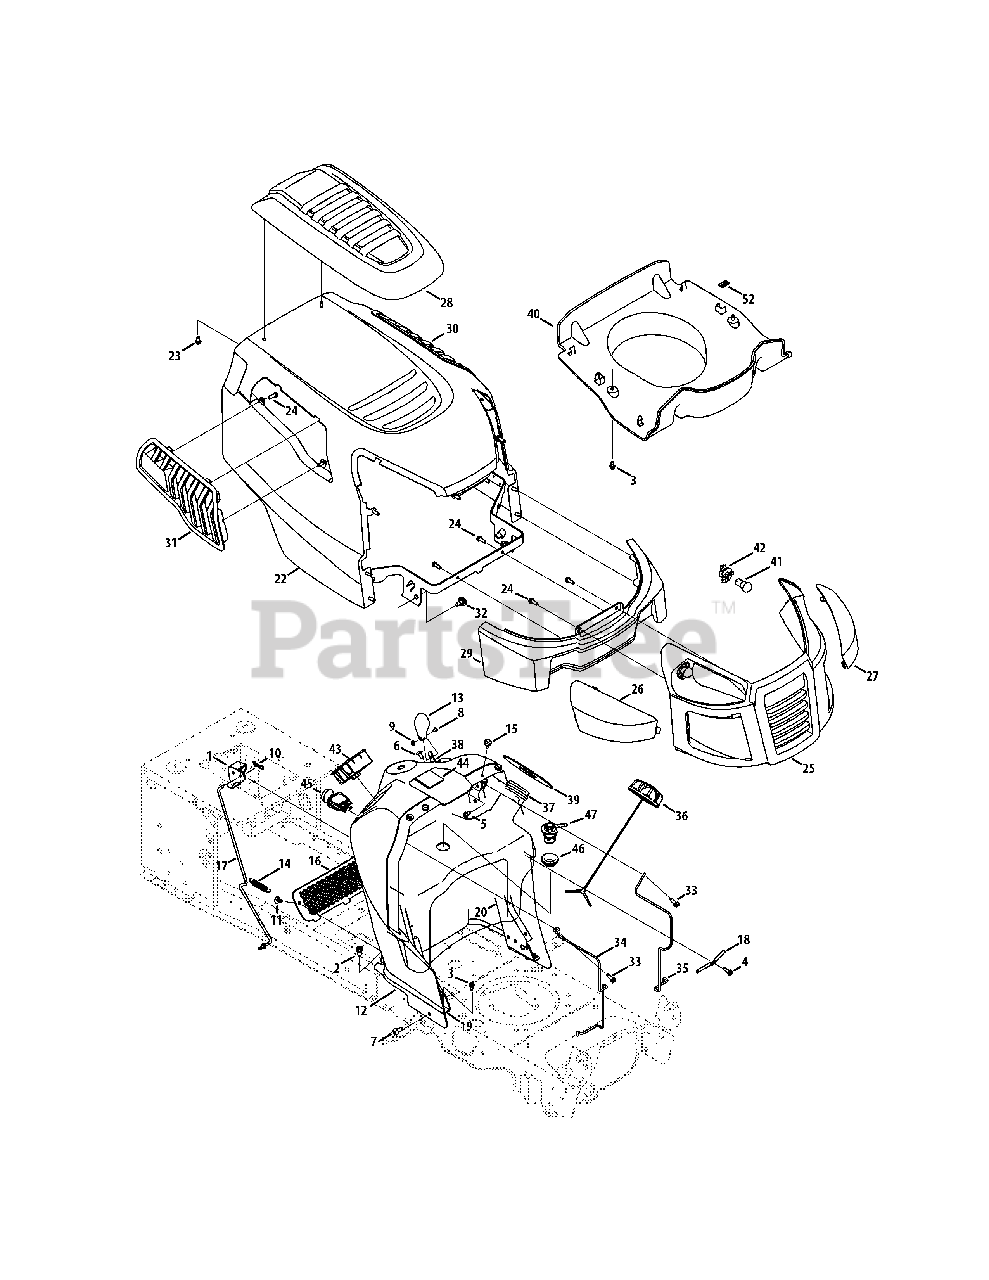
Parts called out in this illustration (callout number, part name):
1	Dash Lever
2	Taptite Screw, Lock Washer, 5/16-18:.750
3	Taptite Screw, Lock Washer, 1/4-20:0.500
4	Hi-Lo Screw, Lock Washer, 1/4-15:0.750
5	Screw, Lock Washer, 1/4-20:0.625
6	Screw, 1/4-14:0.625
7	Taptite Screw, 5/16-18:0.750
8	Machine Screw, #8-32:0.375
9	Hex Nut, #8-32:GRA
10	Bow-tie Cotter Pin
11	Ratchet Clip:.250 DIA
13	Control Knob
14	Extension Spring, .500 DIA X 2.733 LG
15	Bumper
16	Accessory Net
17	Control Rod Latch
18	Lever Rod
19	RH Dash Support Plate
20	LH Dash Support Plate
21	Keys (Set of 2)
22	Hood Assembly
23	Hi-lo Screw, Lock Washer, 1/4-15:0.50
24	Screw, Lock Washer, 1/4 DIA:.750
26	RH Lens
27	LH Lens
28	Hood Scoop
29	Lower Grill
30	LH Hood Scoop
31	RH Hood Scoop
32	Shoulder Screw, .43X.29:TT:5/16-18
33	Taptite Screw, 1/4-20:0.750
34	RH Tank Support Rod
35	LH Tank Support Rod
36	Fuel Cap
37	Fuel Tank, 2.75 Gallons
37	Fuel Tank, 2.06 Gallons CARB
38	Throttle/Choke Control
39	Fuel Tank Gasket
40	P-Style Plen
41	Miniature Lamp, 12V
42	Lamp Socket
43	Switch Key Module
44	Hour Meter
45	PTO Switch
46	Rubber Grommet
47	Fuel Rollover Valve
